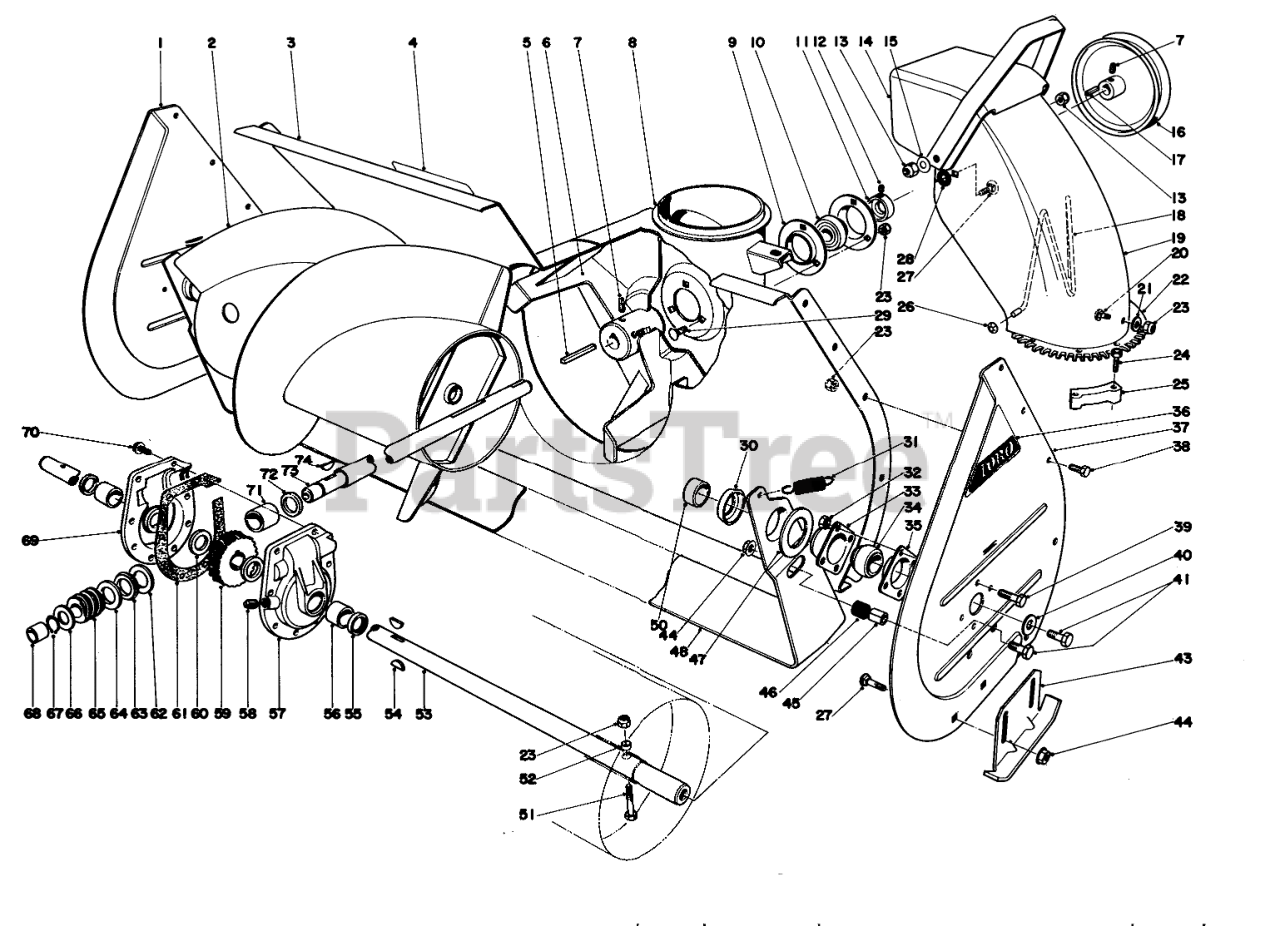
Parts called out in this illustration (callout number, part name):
1	Side Plate
2	RH AUGER ASM - 32"
3	AUGER HSG WA 32" R
4	Decal-Warning
6	IMPELLER ASM
7	SCREW-SET, SQH
8	CHUTE RING
9	BRG FLANGE
10	BALL BRG W/COLLAR
11	EXT LOCKING COLLAR
12	SCREW-HSH
13	NUT-LOCK, CONE
14	Deflector
15	WASHER-BELLEVILLE
16	1/2 X 9.5 DIA PULLEY
17	SQUARE KEY
18	WIRE-CHUTE
19	Upper Chute
20	SCREW-CARR
21	WASHER-PLAIN
22	Screw
23	NUT-LOCK, NI
24	SCREW-SPECIAL
25	RETAINER-CHUTE
26	NUT-PUSH
27	SCREW-CARR
28	WASHER-RUBBER
29	BOLT-CARR
30	Positioner-Scraper
31	SPRING-TENSION
32	NUT-LOCK, CONE
33	BEARING-FLANGE, FRONT
34	BEARING
35	BEARING-FLANGE, REAR
36	AUGER SIDE PLT DECAL
37	Side Plate L. H.
38	SCREW-HH
39	SCREW-HH
40	WASHER
41	SCREW-HH
43	AUGER SKID WA R
44	NUT-HF
45	SCRAPER STOP SPACER
46	SCRAPER STOP CUSHION
47	SCRAPER BLADE SPACER
48	SCRAPER BLADE 32" R
50	AUGER SPACER
51	Auger Bolt
52	SPACER-HUB, AUGER
53	32 AUGER SHAFT
54	KEY-WOODRUFF
55	SEAL-OIL
56	BUSHING
57	Gear Case L.H. (Incl. Ref. #55-56)
58	PLUG-PIPE, SQH
59	GEAR-WORM, 27T
60	WASHER-THRUST
61	Gasket
62	WASHER-THRUST
63	BEARING-THRUST
64	THRUST-WASHER
66	WASHER-THRUST
67	Ring-Snap
68	BUSHING
69	Gear Case R.H. (Incl. Ref. #55-56)
70	SCREW-HWHTF
71	BUSHING-SPECIAL
72	RING-QUAD
73	SHAFT-IMPELLER
74	KEY-WOODRUFF
